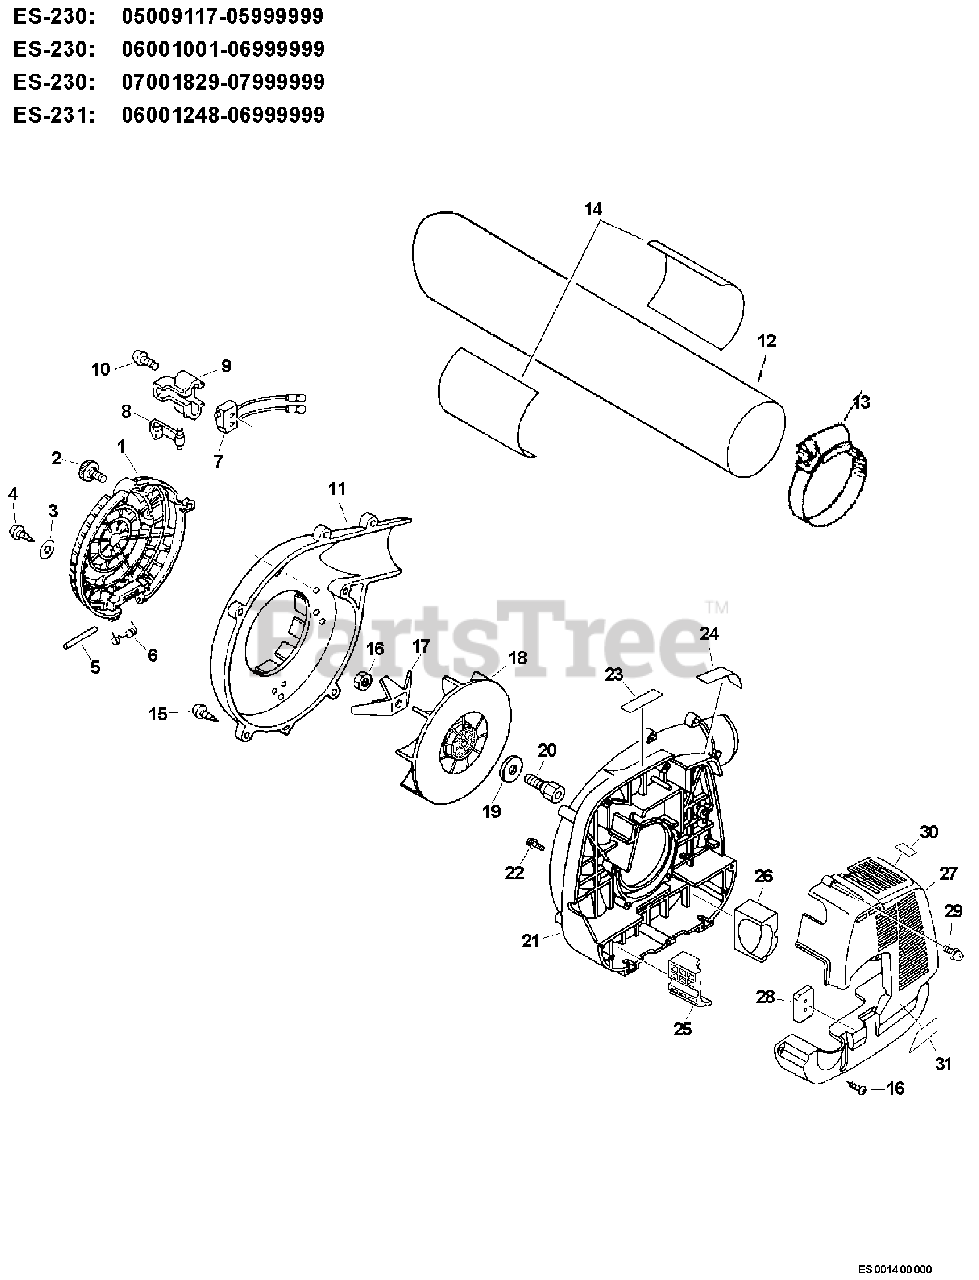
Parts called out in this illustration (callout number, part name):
1	GUARD, DEBRIS
2	THUMBSCREW
3	WASHER - 5
4	SCREW - 5X14
7	IGNITION SWITCH ASSY
8	LEVER, SHUT OFF ACTUATOR
9	BRACKET, SWITCH - GRAY
10	SCREW - 4X22
11	COVER, FAN - LEFT
12	TUBE, VACUUM
14	LABEL - SHRED 'N' VAC
15	SCREW - 5X20 -- TAPPING
17	BLADE, SHREDDER
19	WASHER - 8
20	HUB, FAN
21	COVER, FAN - RIGHT
22	SCREW - 5X20
23	LABEL - NOISE 70dB(A) CAT II
24	LABEL - CAUTION
25	CUSHION, FUEL TANK - LEFT
26	CUSHION, FUEL TANK - RIGHT
27	COVER, ENGINE
28	CUSHION, FUEL TANK - FRONT
29	SCREW - 5X20
30	LABEL - HOT SURFACE
31	LABEL - MODEL ES-231
31	LABEL - MODEL ES-230
